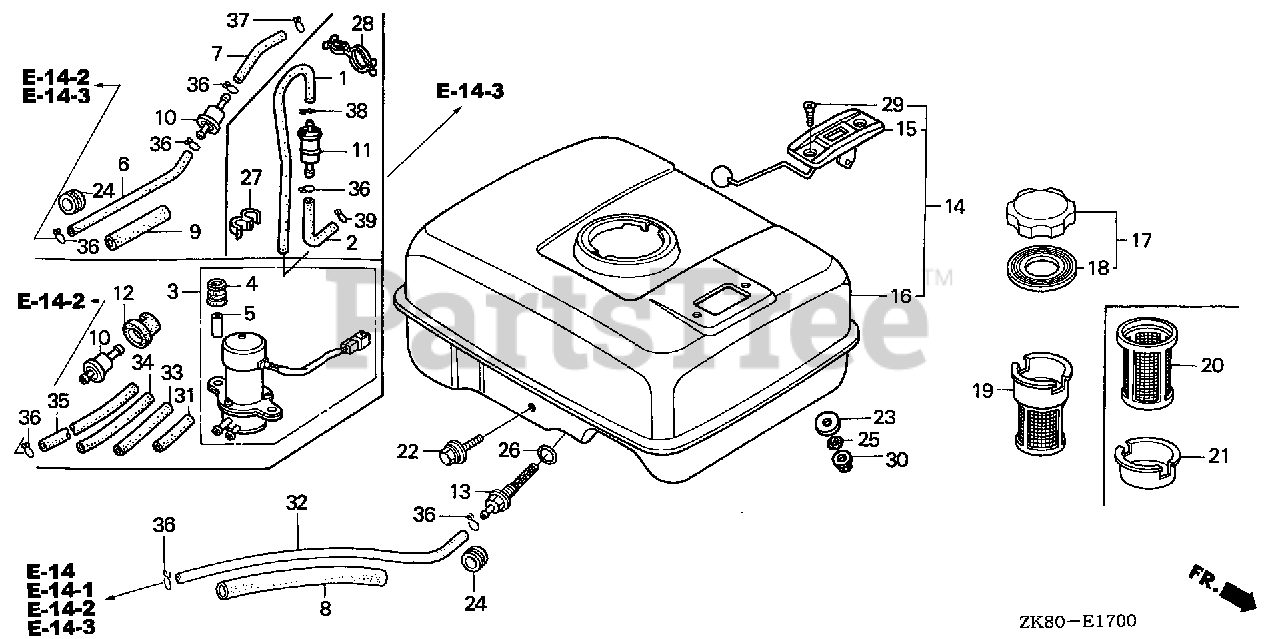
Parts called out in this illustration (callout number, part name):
8	RUBBER, SUPPORTER (107MM)
13	JOINT, FUEL TANK
16	TANK, FUEL *NH31* (MCKINLEY WHITE)
17	CAP, FUEL FILLER (CHROME PLATED)
18	GASKET, FUEL FILLER CAP (39X62X3) (TOUYOUSYA)
22	BOLT, FLANGE (6X29)
26	O-RING (14MM) (ARAI)
26	O-RING (14MM) (NOK)
30	NUT, FLANGE (6MM)
32	BULK HOSE, FUEL (4.5X3000) (4.5X140)
36	CLIP, TUBE (B8)
